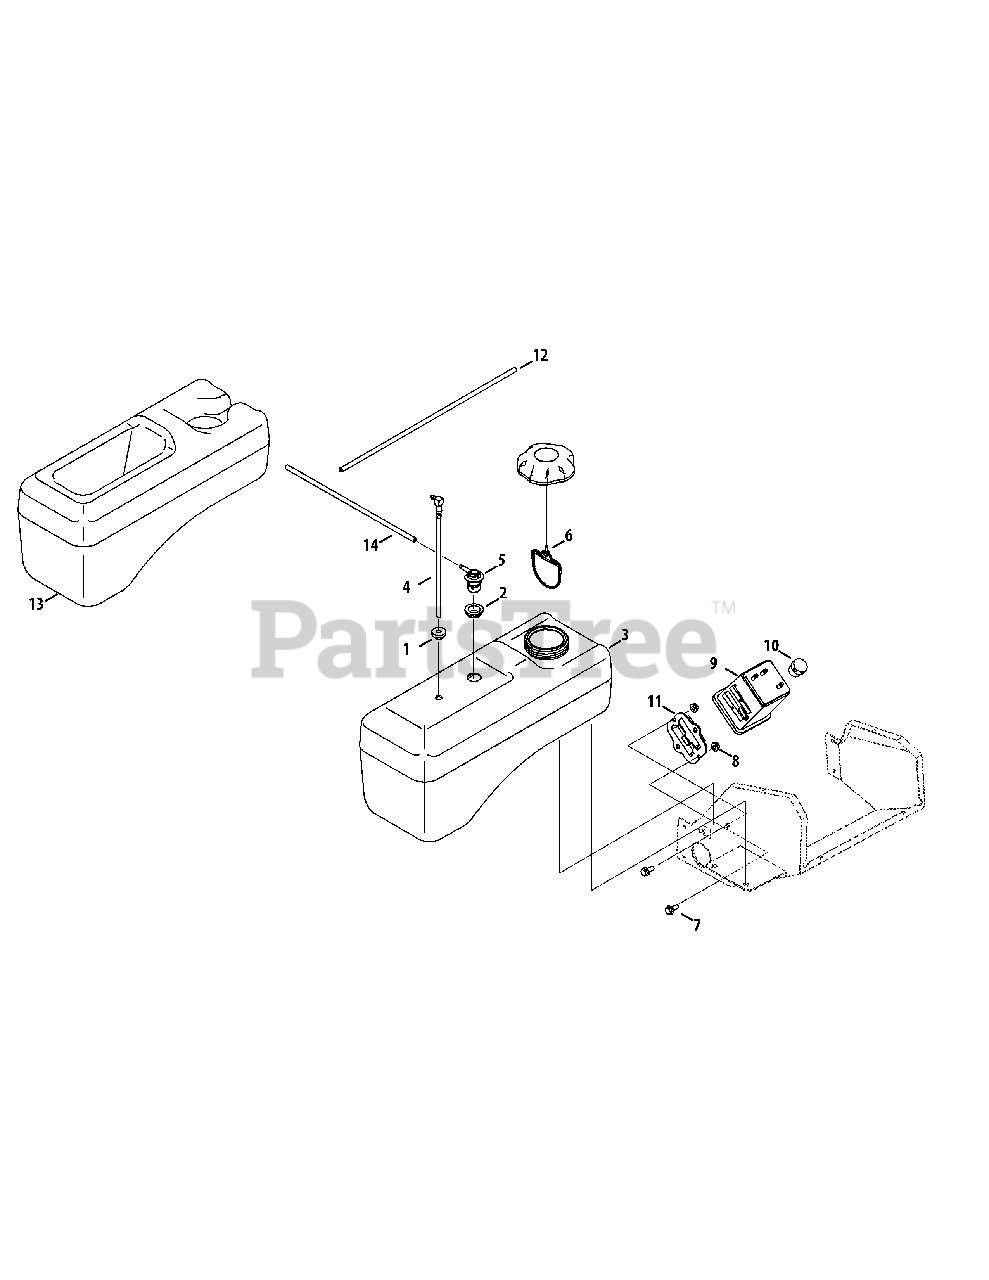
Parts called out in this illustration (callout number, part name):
1	Fuel Tank Bushing
2	Rubber Grommet
4	Fuel Pickup Fitting
5	Rollover Valve
7	Hex Flange Screw, 5/16-18
8	Flange Lock Nut, 5/16-18
9	Carbon Cannister
10	Cannister Filter Vent
11	Cannister Adapter Bracket
12	Low Perm Fuel Host 7/32 Yellow
13	Utility Bin
14	Vent Hose 3/16 Red
